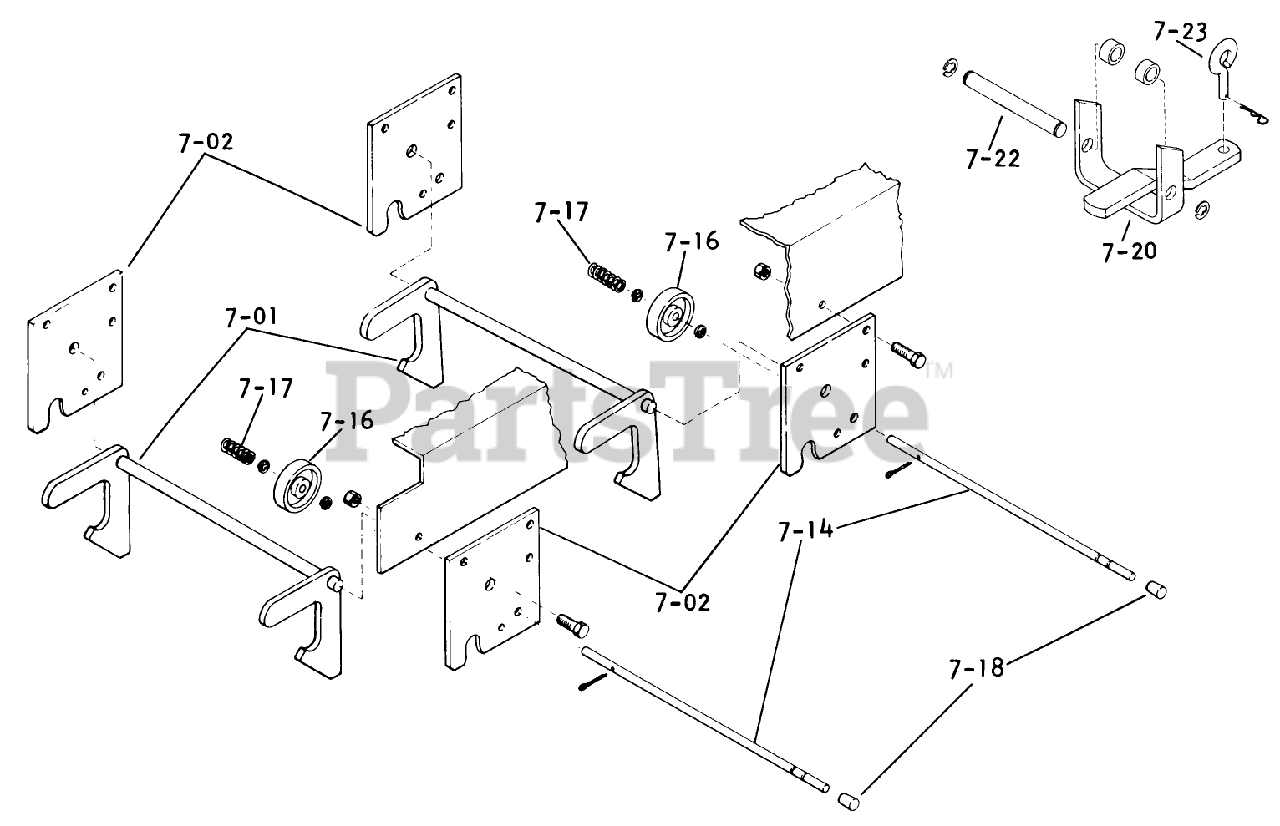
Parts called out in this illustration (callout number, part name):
7-16	Lock Rod
7-17	SPRING-COMPRESSION
7-18	CAP-ROD, PLUNGER
7-22	PIN-STATIONARY HITCH
7-22	E-RING
7-23	Hairpin
